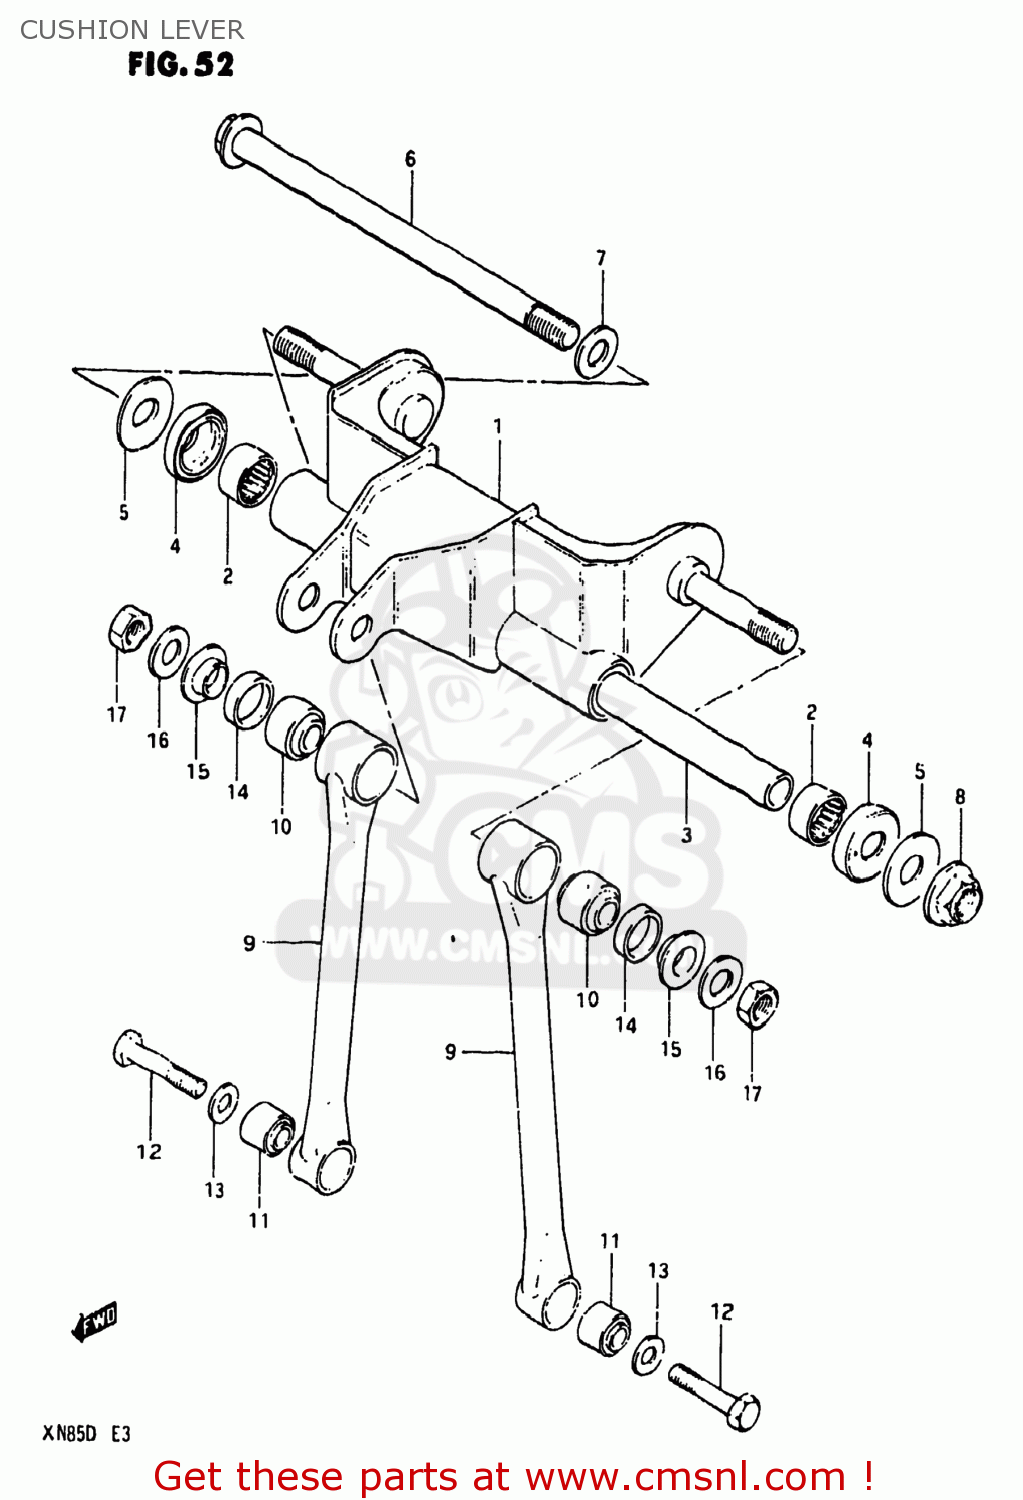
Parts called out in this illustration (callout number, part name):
1	ROD SET,REAR CUSHION LEVER
2	ROLLER BEARING (17X24X2
3	SPACER,REAR CUSHION LEVER
4	COVER,RR SWGARM DUST SEAL
5	WASHER
6	SHAFT,REAR CUSHION LEVER
7	WASHER
8	NUT
9	LEVER SET,REAR CUSHION
10	BEARING
11	BUSH
12	BOLT
13	WASHER
14	DUST SEAL, UPPER
15	SPACER,REAR SHOCK ABSORBER
16	WASHER
17	NUT
